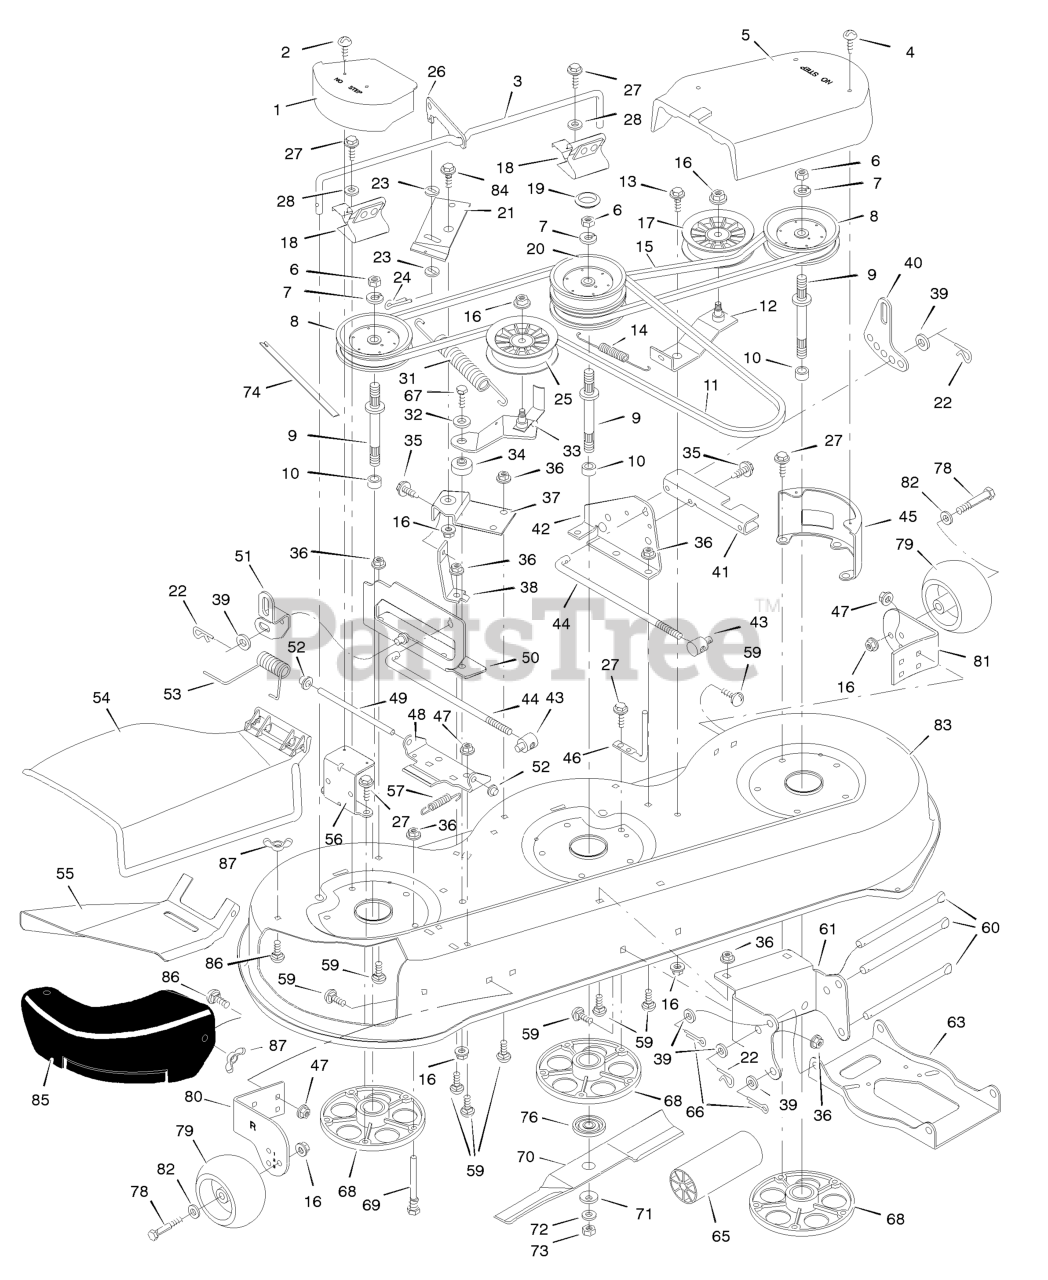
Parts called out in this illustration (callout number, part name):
1	Cover, Pulley
3	Rod, Brake
5	Cover, Left Pulley
6	Nut, Hex
7	Lockwasher
9	Jackshaft
10	Spacer, Bearing
11	Belt, Primary Mower Drive
12	Bracket, Idler
13	Bolt, Shoulder
14	Spring, Extension
15	Belt, Secondary Mower Drive
16	Locknut
17	Pulley, Idler
18	Spring Assembly, Brake
20	Pulley, Stack
21	Bracket, Pivot
22	Pin, Hair
24	Pin, Cotter
25	Pulley, Idler
26	Link, Brake
27	Screw
31	Spring, Extension
33	Bracket, Idler
34	Bushing
36	Nut, Hex
37	Support, Pivot
38	Strut, Pivot
40	Plate, Adjuster
41	Channel, Left Cover
42	Bracket Assembly, Lifter
43	NUT, Adjusting, 1/2-13
44	Rod, Adjuster
45	Bracket, Left Cover
46	Guide, Belt
47	Locknut
48	Bracket, Hinge
49	Rod, Deflector
50	Bracket Assembly, Lifter
51	Link, Suspension
52	Push- On Cap
53	Spring, Torsion
54	Deflector
55	Deflector, Inside
56	Bracket, Cover
59	Bolt, Carriage
60	Rod, Hanger
61	Bracket, Front Hanger
63	Hanger, Front
66	Pin, Cotter
67	Bolt, Hex
68	Housing, Mandrel
69	Guide, Belt
70	Blade
71	Washer, Belleville
73	Nut, Hex
74	Indicator, Plastic
76	Adapter, Blade
78	Bolt, Shoulder
79	Wheel, Gauge
80	Bracket, Right Gauge Wheel
81	Bracket, Left Gauge Wheel
82	Washer
83	Housing, Mower
84	Bolt, Shoulder
85	Plate, Mulcher
86	Bolt, Carriage
87	Wingnut
